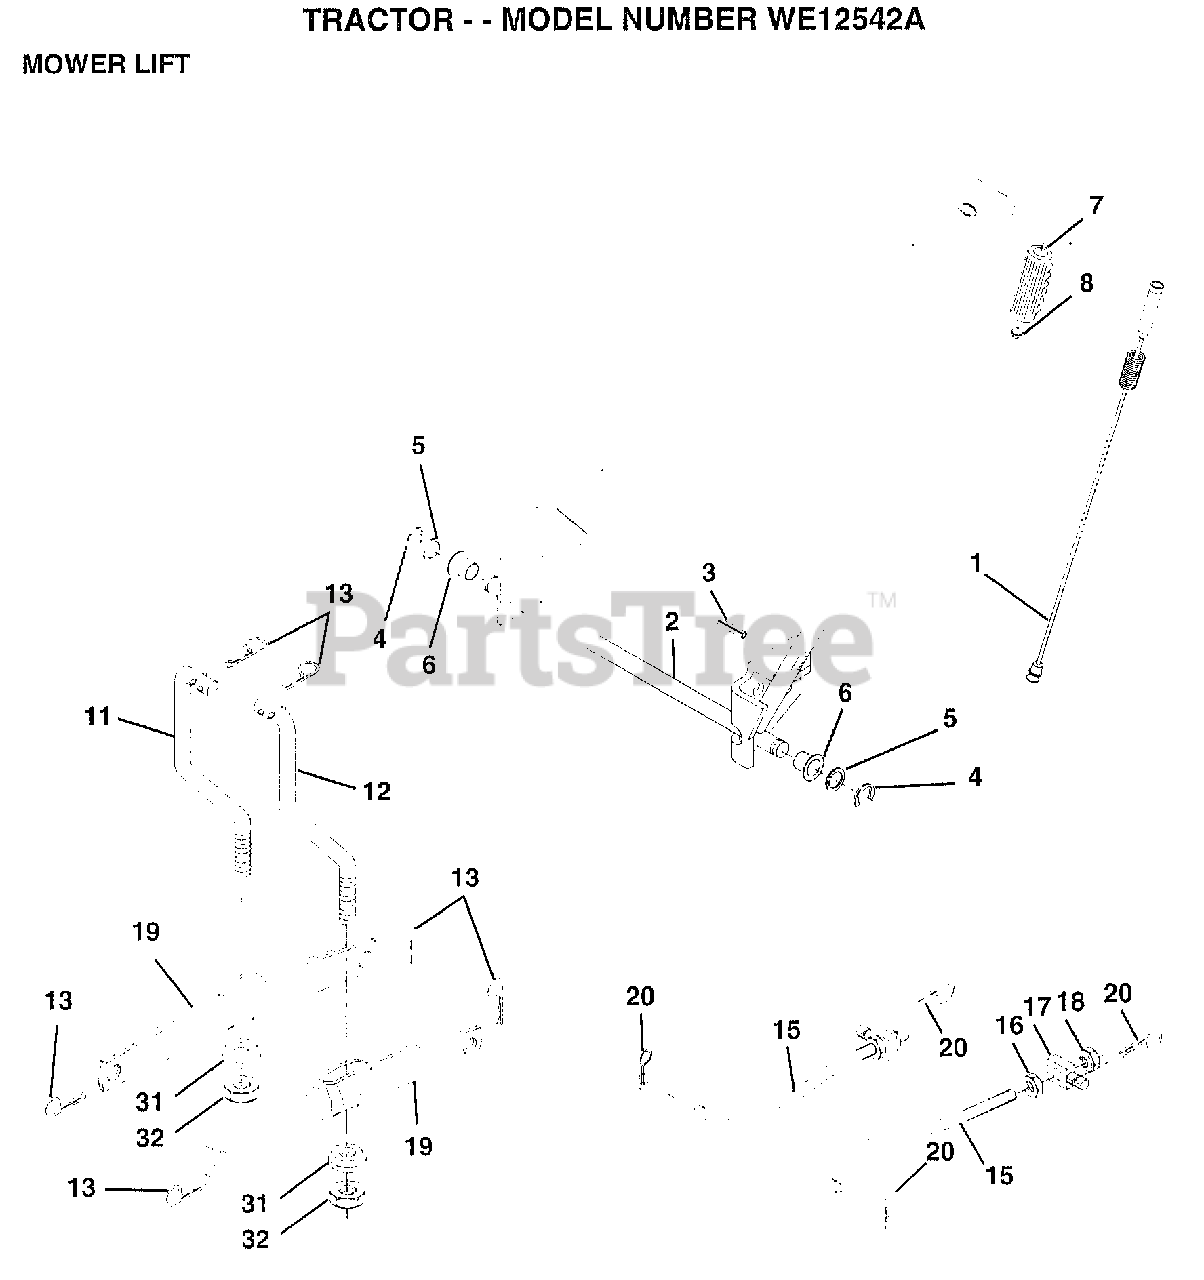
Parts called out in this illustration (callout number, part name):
1	WIRE ASM W.SPRING
2	SHAFT ASM LIFT RH
3	PIN-GROOVE LT
5	WASHER
6	NYLON BEARING
7	GRIP
15	LINK.FRONT
16	NUT
17	TRUNION
18	NUT.LK.W/WSH.1/2.
19	ARM SUSP REAR
31	BEARING PVT LH
32	NUT.CROWNLOCK.3/8
